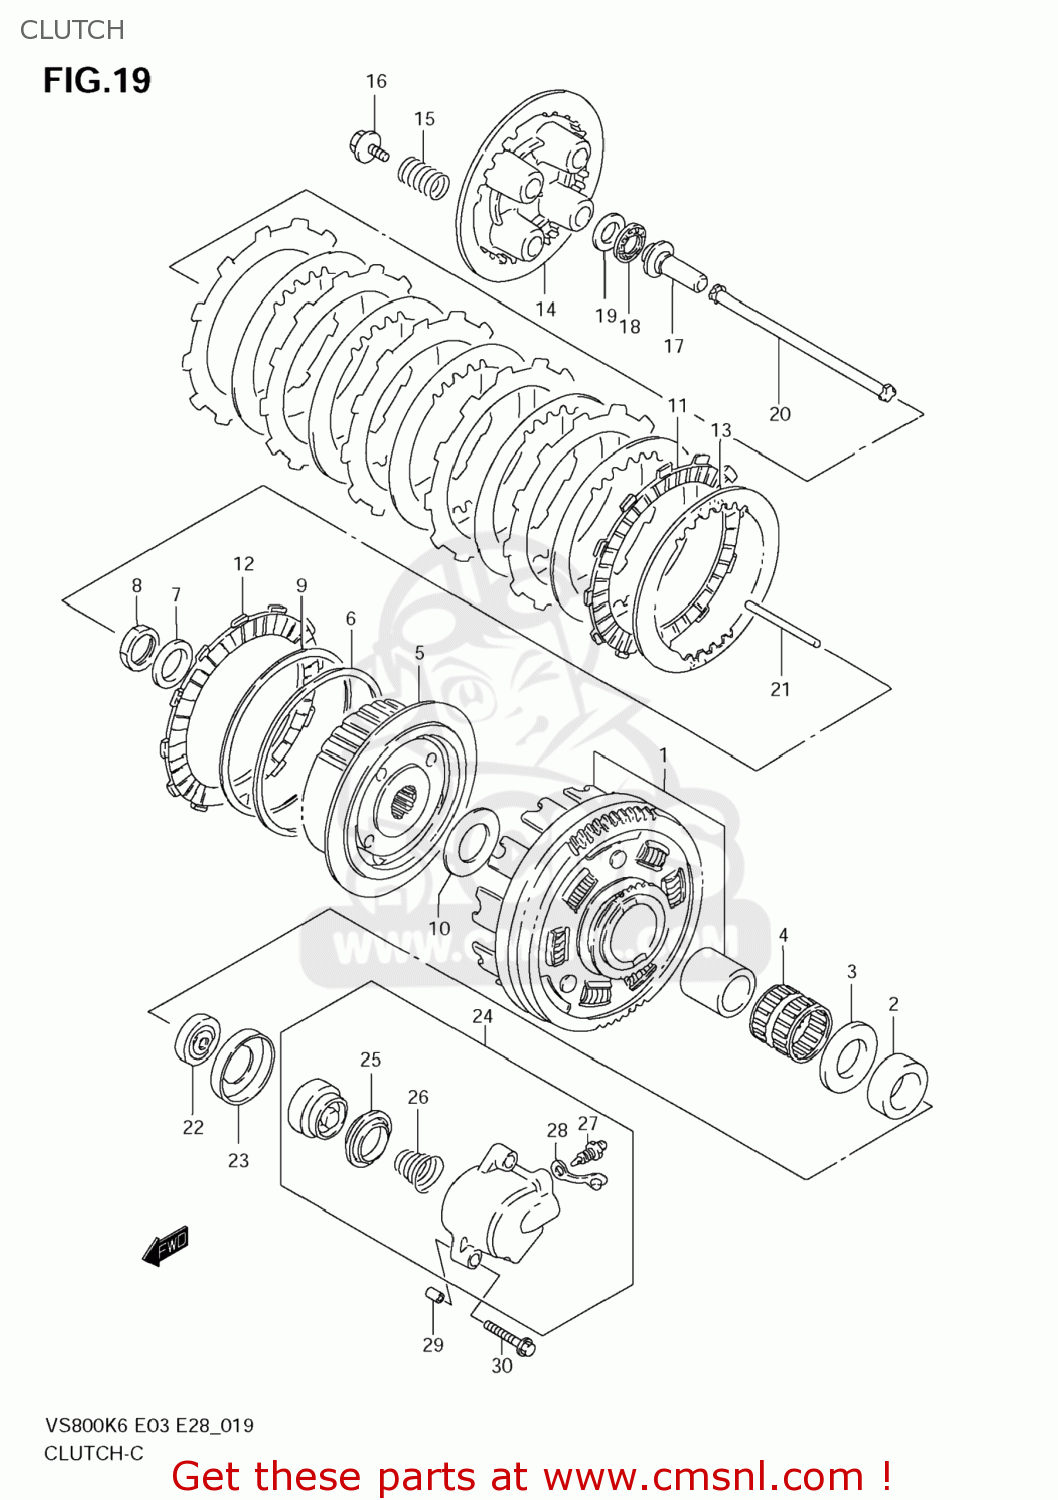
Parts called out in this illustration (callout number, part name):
1	GEAR ASSY,PRIMARY(NT:71)
2	SPACER(25X38X6.5)
3	WASHER(25X50X2.5)
4	BEARING(35X40X35.8)
5	HUB,CLUTCH SLEEVE
6	SEAT,WAVE WASHER(T:1.4)
7	WASHER
8	NUT
9	WASHER
10	WASHER(25X50X2.5)
11	PLATE,CLUTCH DRIVE (NAS)
12	PLATE,CLUTCH DRIVE(T:3.5) (NAS)
13	PLATE,CLUTCH DRIVEN(T:1.6) (NAS)
14	DISC,CLUTCH PRESSURE
15	SPRING
16	BOLT(6X30)
17	PIECE,CLUTCH PUSH
18	BEARING(15X28X2)
19	WASHER(15.5X28X1)
20	ROD,CLUTCH
21	ROD,CLUTCH PUSH,L
22	SEAL,OIL(6X34X11)
23	RETAINER,CL PUSH ROD OIL SEAL
24	CYLINDER,CLUTCH RELEASE
25	CUP,CLUTCH CYLINDER
26	SPRING,CLUTCH CYLINDER
27	BLEEDER
28	CAP,BLEEDER
29	PIN
30	BOLT
